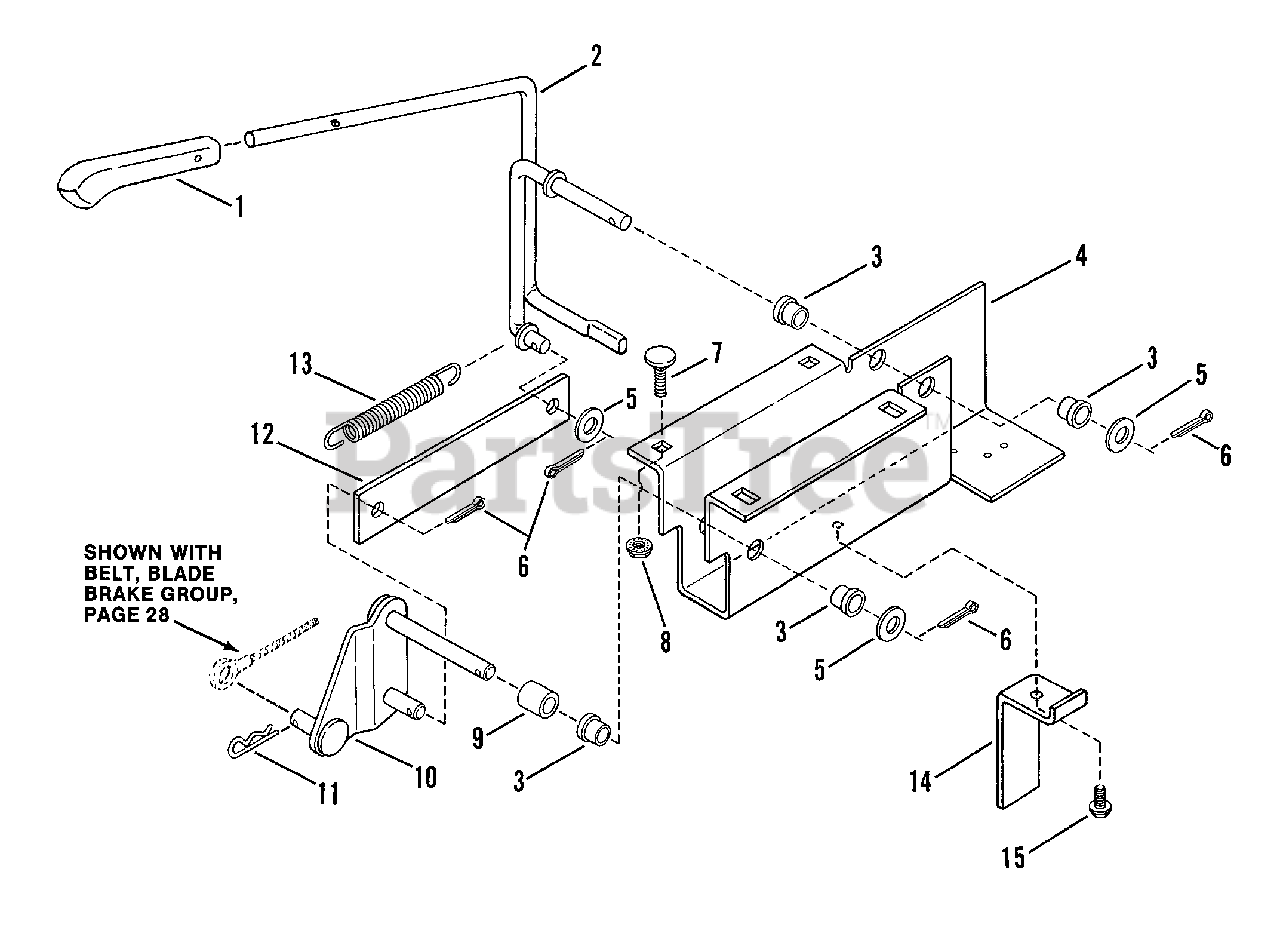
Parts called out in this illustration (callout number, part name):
1	KNOB, Handle
2	HANDLE, Blade Engagement
3	BUSHING
4	BRACKET, Handle
5	WASHER
6	COTTER-PIN, 3/32 x 3/4"
7	BOLT, 1/4-20 x 5/8" Flat Head Carriage
8	LOCKNUT, 1/4-20 Hex Flange
9	SPACER
10	PIVOT ARM ASSEMBLY
11	PIN, Hair
13	SPRING, Return
14	GUIDE, Belt
15	SCREW, #10-24 x 1/2" H.W.H.S.T.
